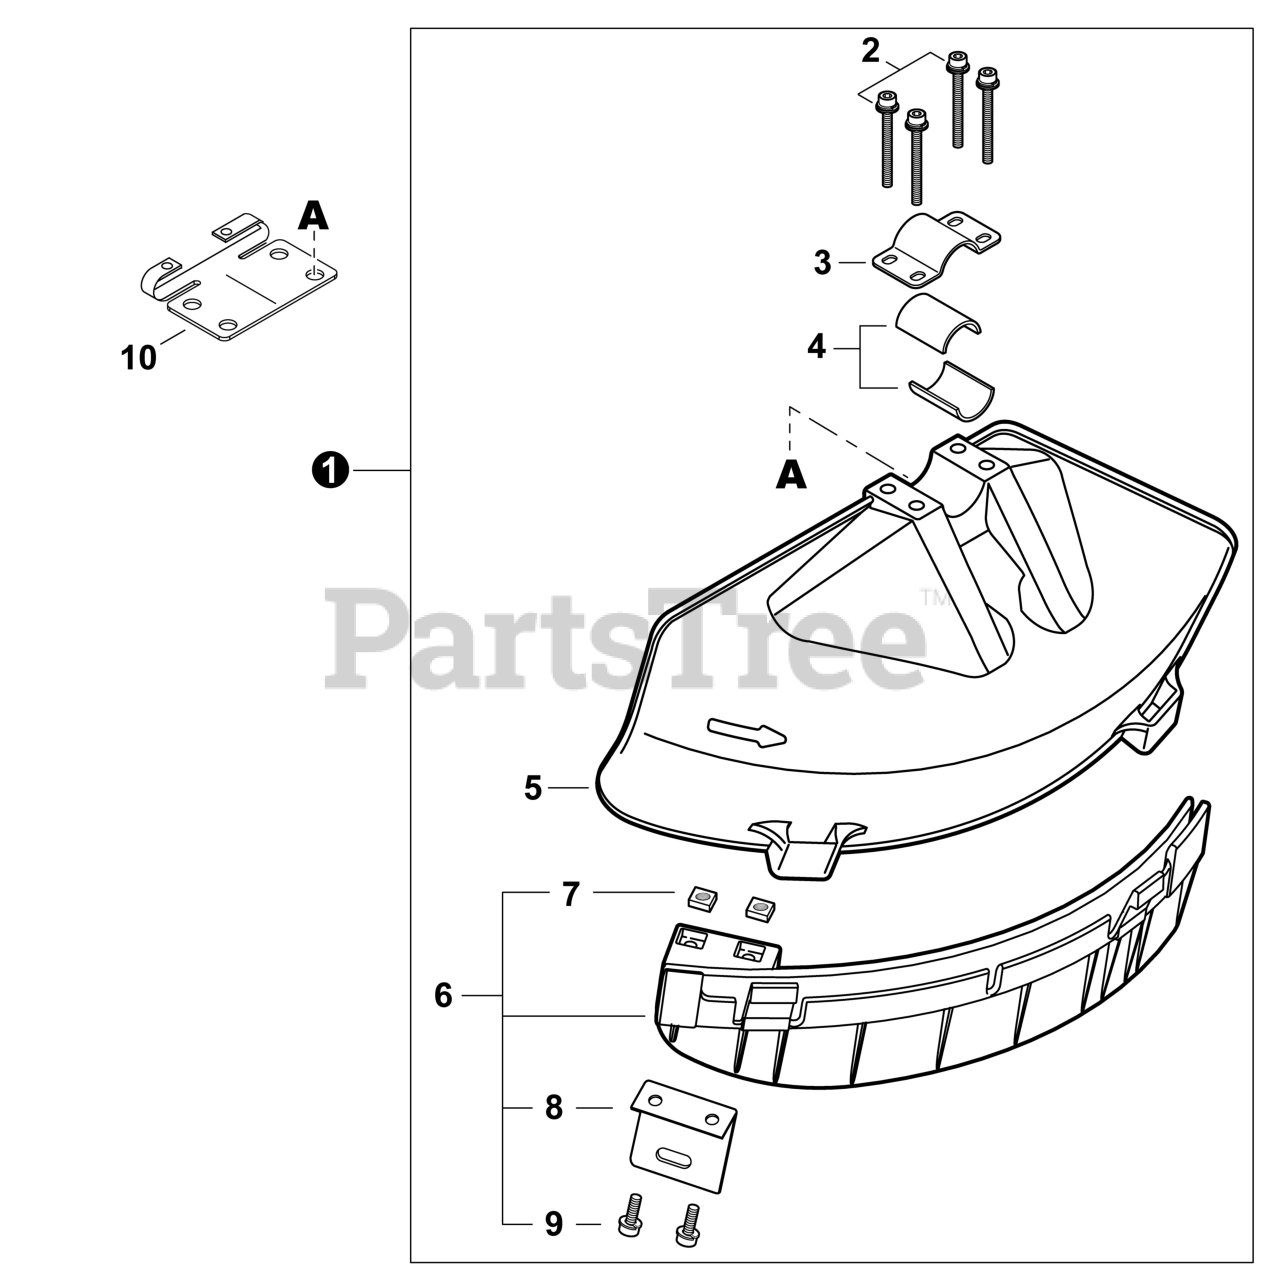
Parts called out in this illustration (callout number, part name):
1	SHIELD KIT, DEBRIS
2	BOLT M5x45
3	CLAMP, UPPER
5	SHIELD, DEBRIS PLASTIC
6	EXTENSION ASSY, DEBRIS SHIELD
9	BOLT 5x16
10	BRACKET, SHIELD
